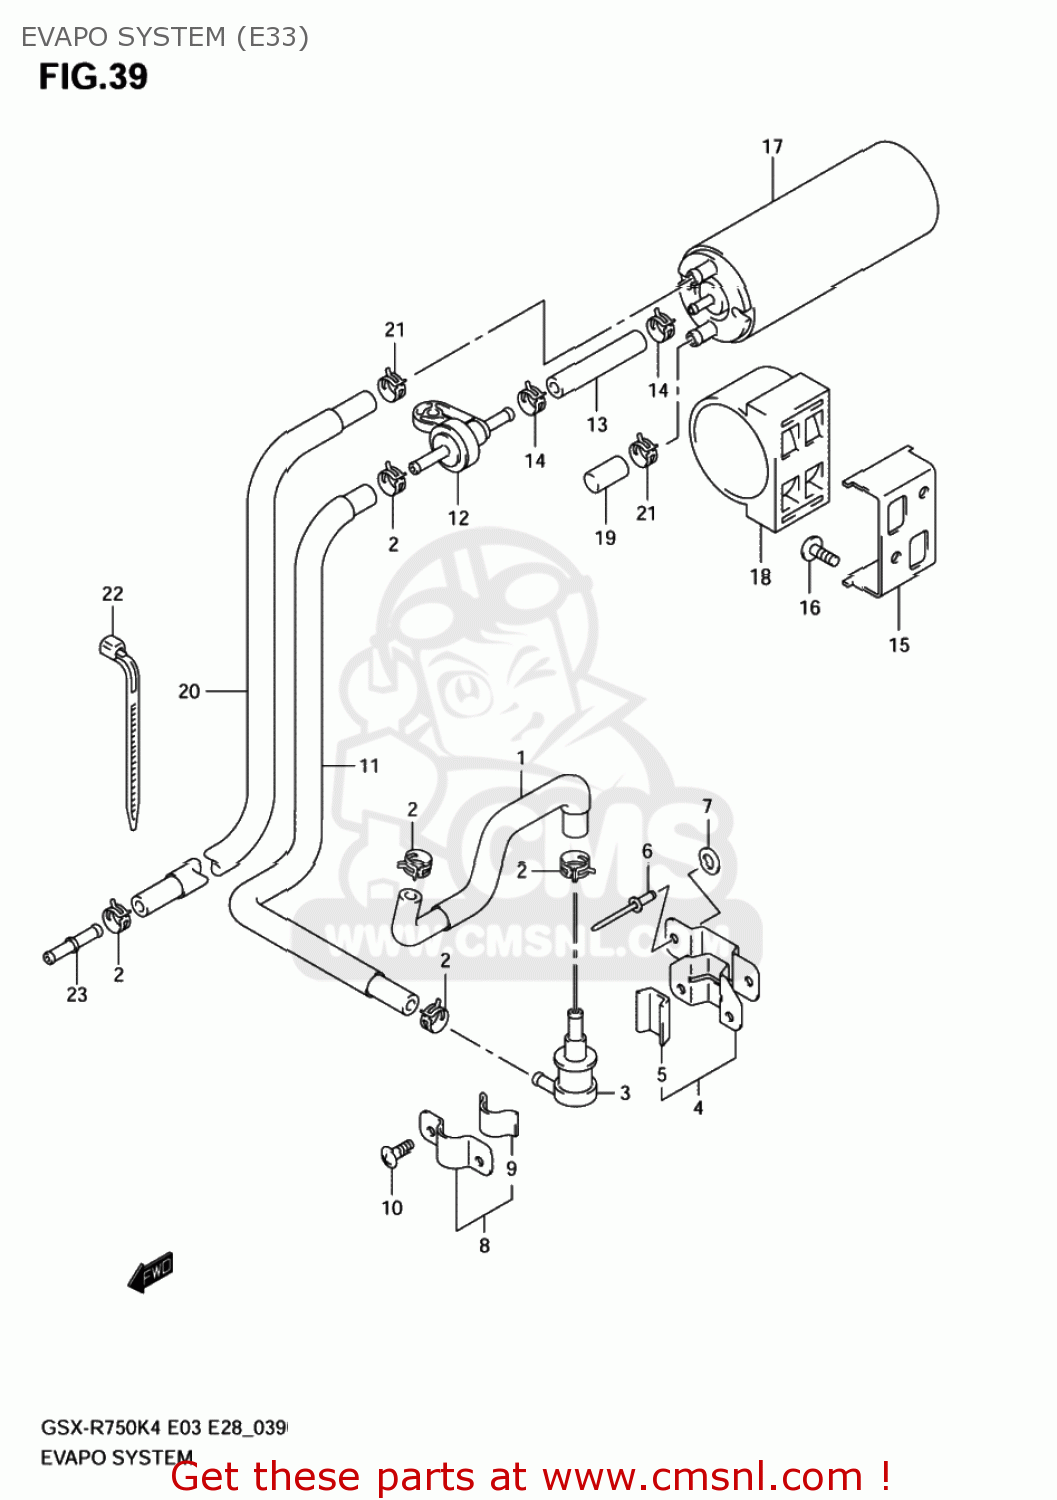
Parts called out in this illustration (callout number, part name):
1	HOSE,TANK & BREATHER VALVE
2	CLIP
3	VALVE,FUEL TANK BREATHER
4	PLATE,BREATHER VALVE
5	CUSHION
6	RIVET
7	WASHER
8	PLATE,FUEL TANK BREATHER NO.2
9	CUSHION
10	SCREW
11	HOSE,BRTHR VALVE & 2 WAY VALVE
12	VALVE,2 WAY & BREATHER VALVE
13	HOSE(5.4X11.4X600)
14	CLIP
15	BRACKET,CANISTER
16	SCREW(6X10)
17	CANISTER ASSY,CHARCOAL
18	CUSHION,CANISTER
19	CAP,OD:11.5
20	HOSE,CSTR PURGE
21	CLIP
22	CLAMP(L:120)
23	JOINT
